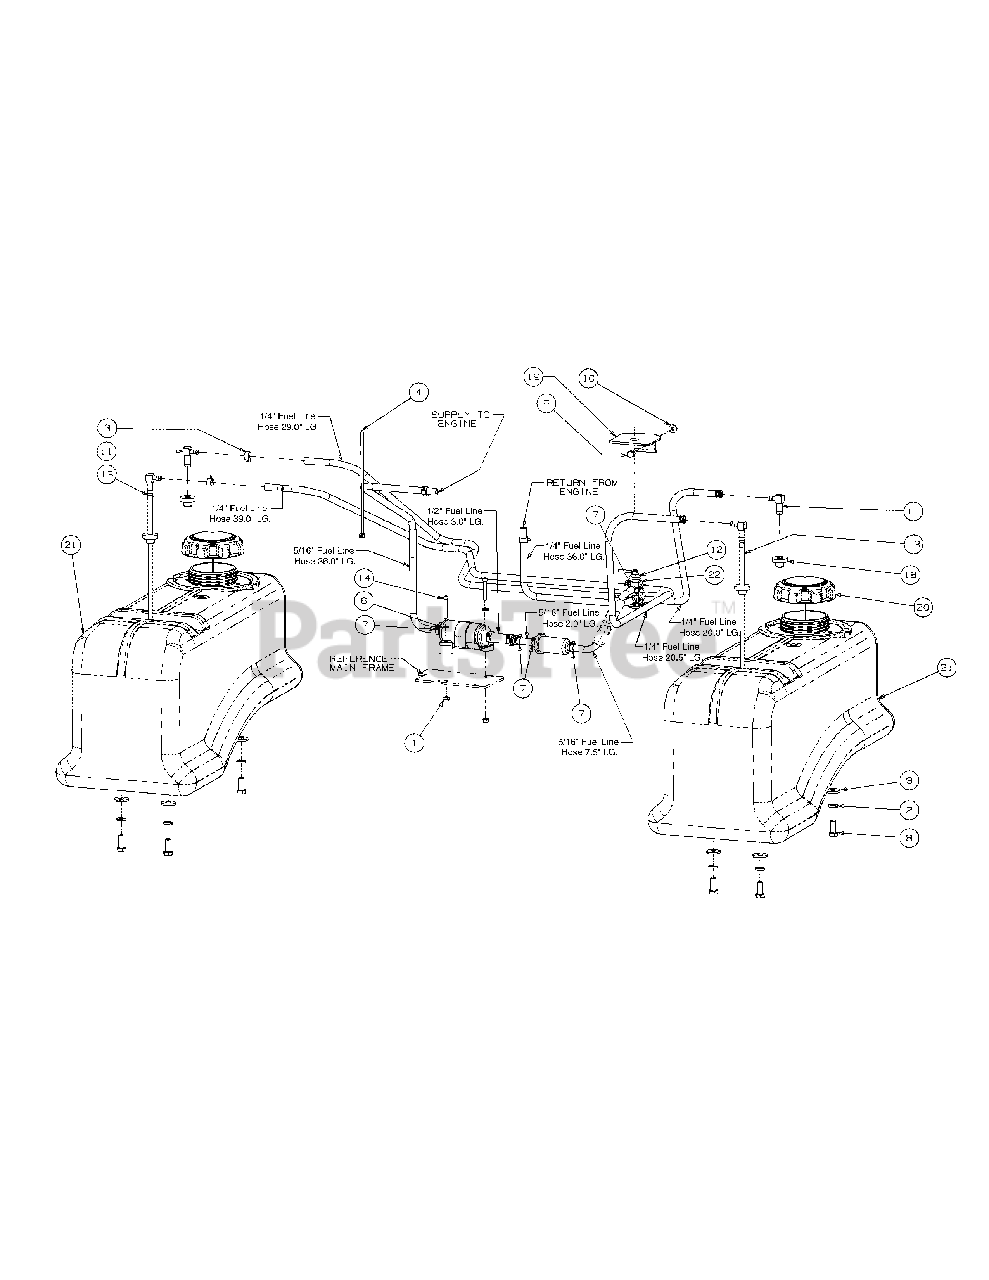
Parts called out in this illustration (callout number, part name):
1	Nut, 10-24, Nylon Insert
2	Lock Washer, 3/8
3	Clamp, Union
4	Cable Tie
5	Hex Cap Screw, 1/4-20 x 3/4
6	Washer, 3/16
7	Hose Clamp
8	Hex, Cap Screw, 3/8-16, .88
9	Flat Washer, .406 ID, 1.0 OD, .105
10	Hex Flange Lock Nut, 1/4-20
11	Fuel Fitting, Return
12	Shut Off Fuel Valve
13	Fuel Fitting, Pickup
14	Socket Head Screw, 10-24 x 1.25
15	Hose, 1/4" Fuel Line
16	Hose, .31 ID x .56 OD Fuel Line
17	Fuel Hose, .50 ID x .75 OD
18	Fuel Tank Grommet
19	Fuel Valve Mounting Bracket
20	Fuel Cap 3.5, Tethered
21	Fuel Tank
22	Lock Washer
